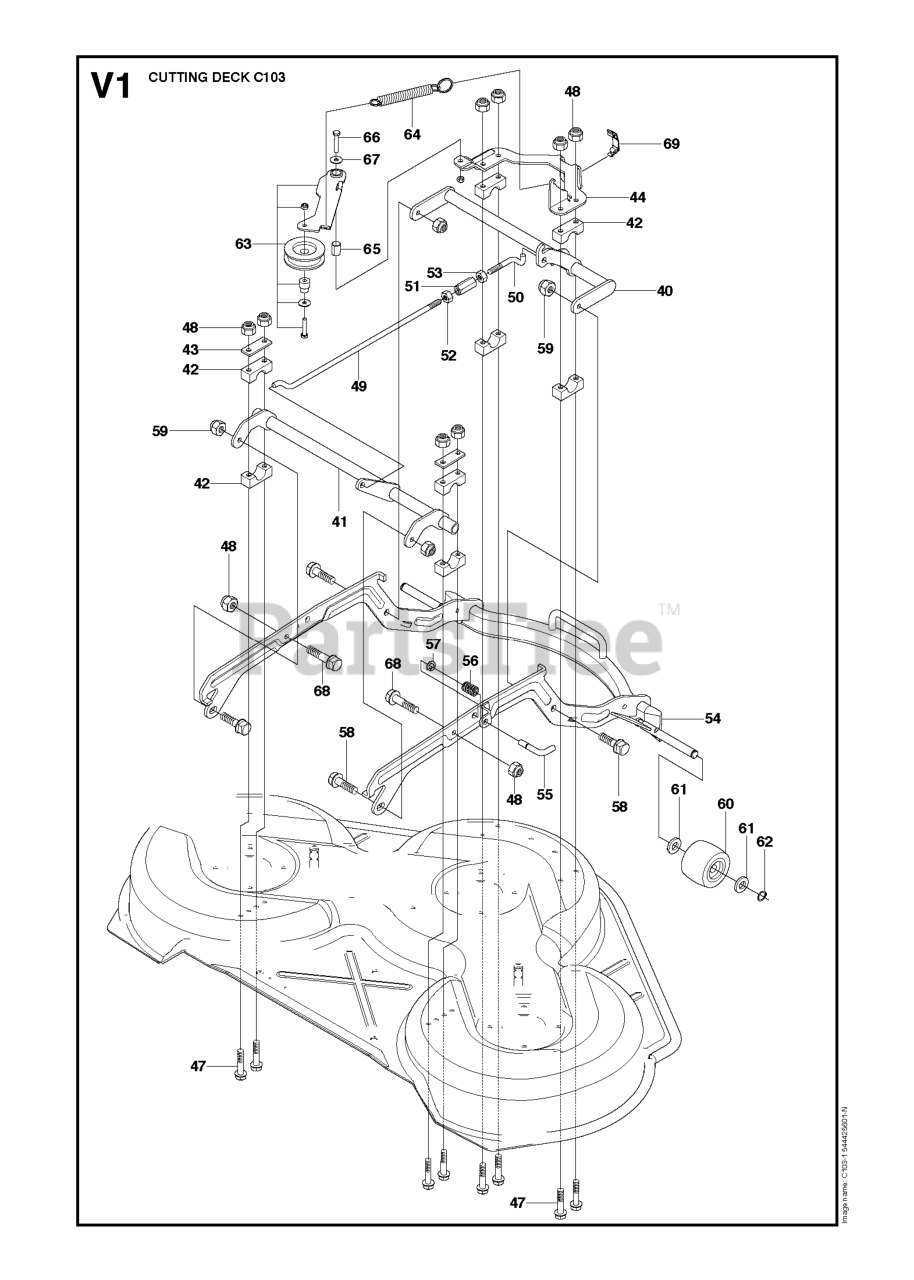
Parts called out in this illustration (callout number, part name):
48	LOCKNUT M8
53	NUT
59	LOCKNUT M8
60	DECK ROLLER, FRONT
62	RETAINING RING SGA 15
66	SCREW
68	COLLAR SCREW
69	CLIP GRAY
